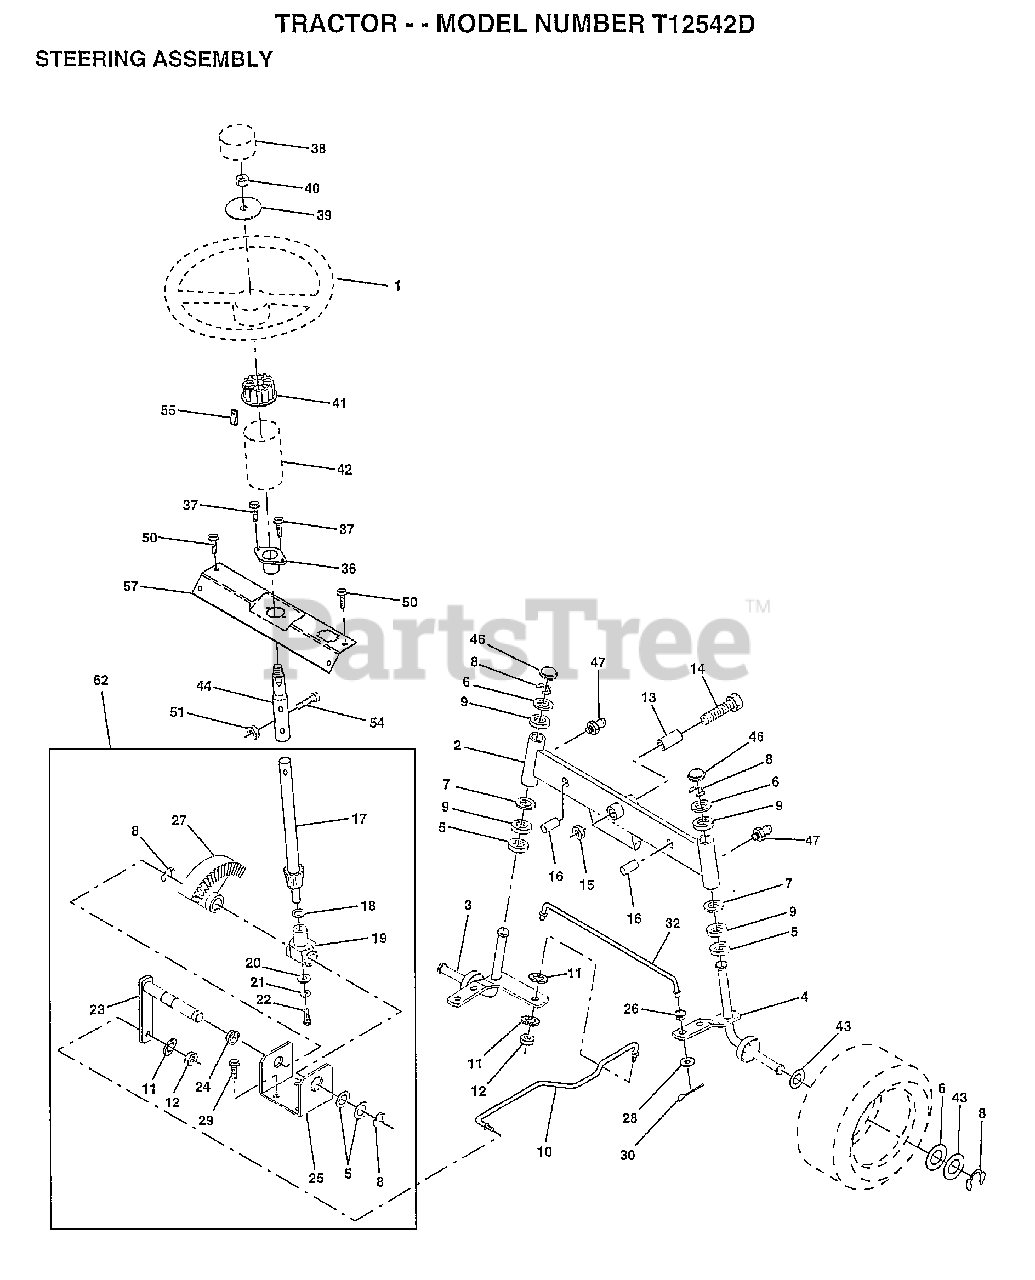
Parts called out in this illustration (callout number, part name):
2	AXLE ASM FRONT
3	SPINDLE LH
4	SPINDLE RH
5	WASHER .T
6	WASHER
7	WASHER
8	RING
9	COL. SRTG. BEAR.
11	LOCKWASHER
13	BEARING
14	BOLT HEX 5/8-11
15	"NUT-LOC,FLANGE LT"
16	AXLE PIN
17	SHAFT ASM STEERIN
18	THRUST WASHER
19	SUPPORT.SHAFT
21	LOCKWASHER
22	SCREW.SCKTHD.CAP
24	NYLINER T
25	"BRKT,STEERING"
26	BUSHING.DRAGLINK
27	GEAR SECTOR
28	WASHER
29	SCREW
30	COTTER PIN
32	TIE ROD
38	ST WHL INSERT CAP
39	WASHER T
40	GRIPCO NUT
41	ADAPTER-WHEEL LT
42	BOOT SHAFT STEER
44	SHAFT EXT STEER
46	CAP
47	ZERK M
50	SCREW HEX CRT
51	NUT
54	BOLT
55	CLIP TINNERMAN
57	SUPPORT SHAFT STR
